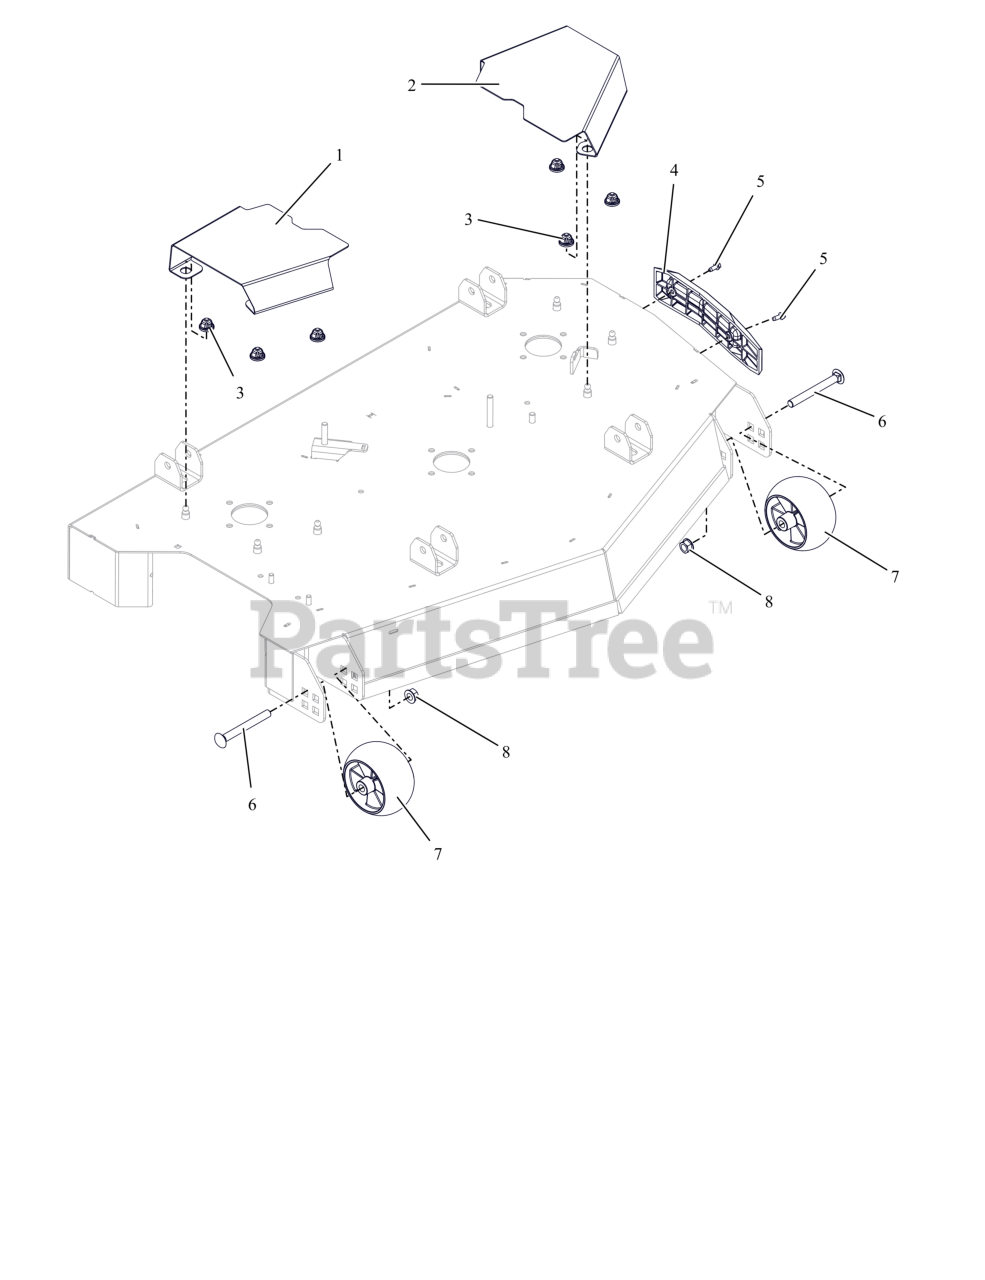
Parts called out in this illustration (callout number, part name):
1	COVER- RIGHT BELT
2	COVER- LEFT BELT
3	GROMMET, 10MM BOLLHOFF
4	BUMPER- DECK
5	SCR,TAP .25-20X.625 HWH ZCC
6	BLT,RHNS .50-13X4.50 G5 ZCC NS
7	WHEEL, ANTI SCALP - 5X3 CTR W/RIBS
8	NUT-LK-CTR-FLG .500-13 GG ZCC
